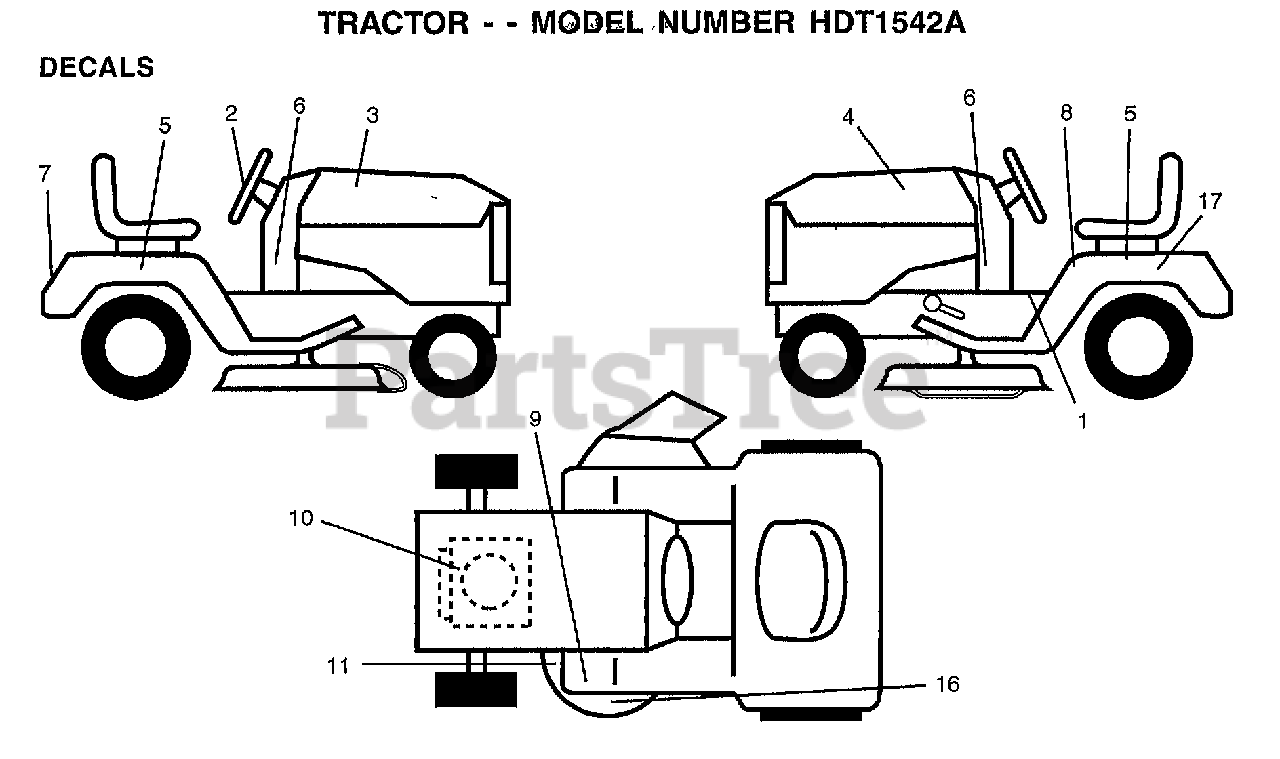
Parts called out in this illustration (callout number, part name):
2	"DECAL WHEEL,STEER"
3	DECAL.HOOD.RH.
4	DECAL.HOOD.LH
5	DECAL.FENDER.SD.LAWN
7	"DECAL FENDER,LOGO"
8	"DECAL FENDER,DANG"
9	DECAL CLUT/BRAKE
11	"DECAL-SCHEM,BELT"
16	"DECAL DECK,MULCH"
17	DECAL.BATRY.3-3908
